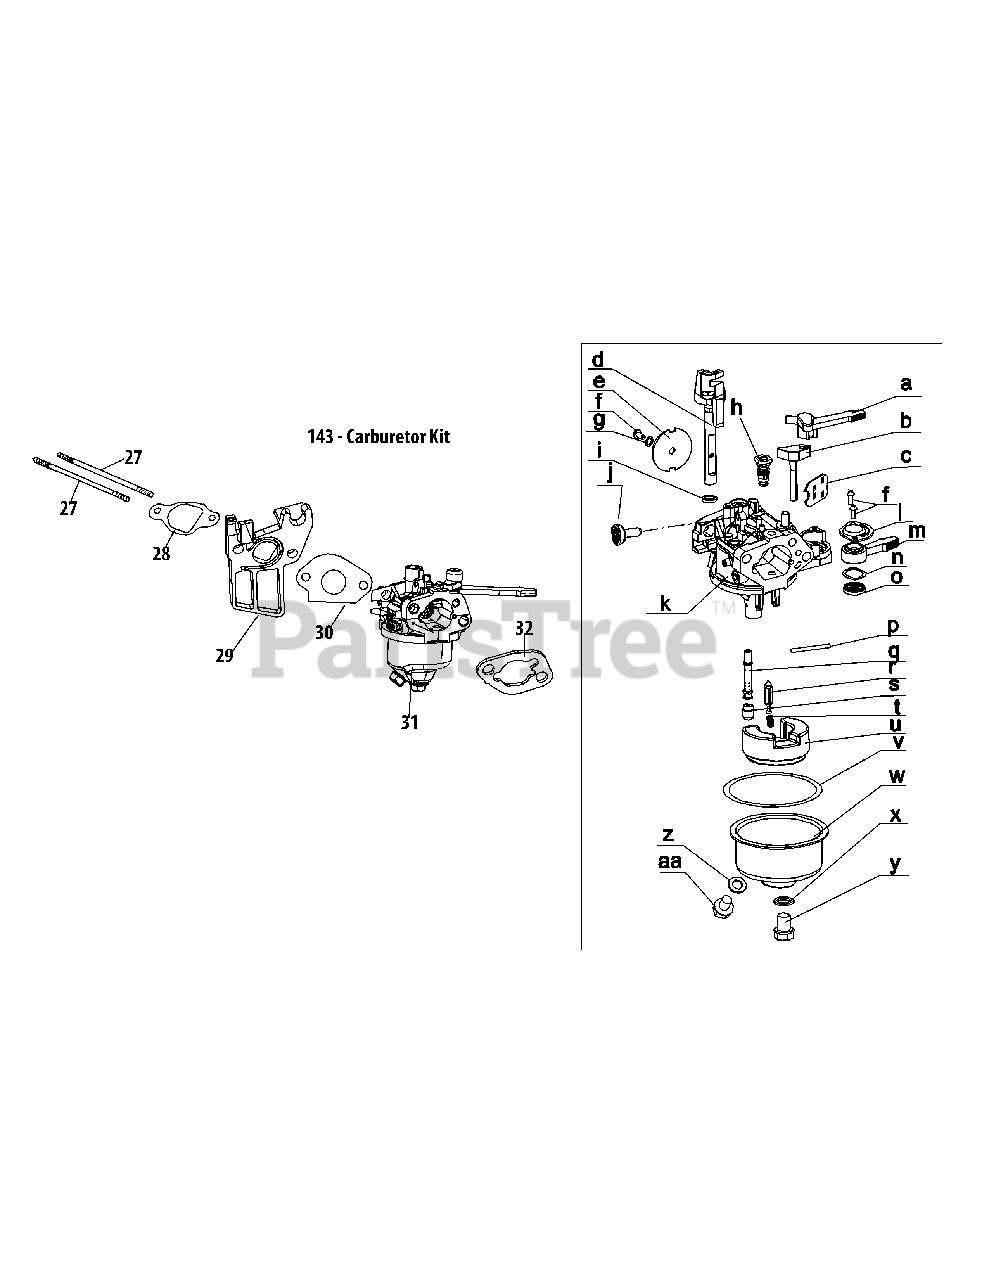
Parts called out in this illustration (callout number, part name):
27	Stud M6×110
28	Carburetor Insulator Gasket
29	Carburetor Insulator
30	Carburetor Gasket
31	Carburetor Assembly
32	Carburetor Gasket Plate
143	Carburetor Kit Dn-170
